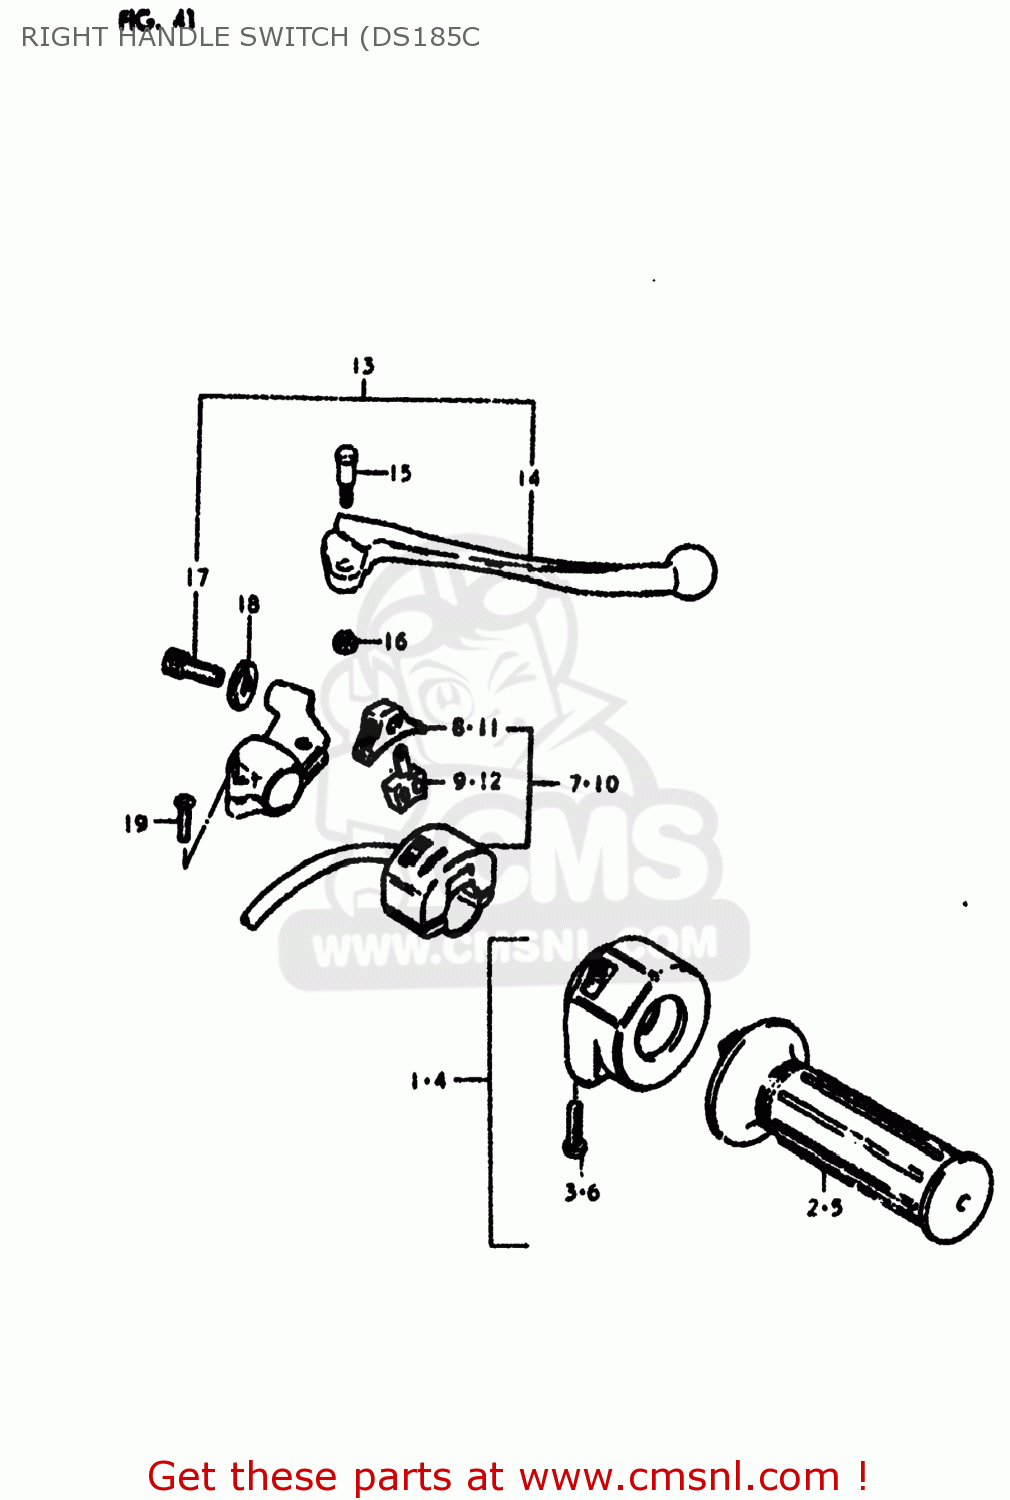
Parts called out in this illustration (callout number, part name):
1	GRIP ASSEMBLY,THROTTLE
2	GRIP,THROTTLE
3	SCREW 5X20
4	CASE ASSEMBLY,THROTTLE
5	GRIP,THROTTLE
6	SCREW
7	SWITCH ASSEMBLY,LIGHTING
8	KNOB,HANDLE SWITCH
9	BLOCK,LIGHTING/DIMMER
10	SWITCH ASSEMBLY,LIGHTING
11	KNOB,LIGHTING & DIMMER
12	BLOCK,LIGHTING/DIMMER
13	LEVER ASSEMBLY,BRAKE
14	LEVER,BRAKE
15	BOLT,LEVER
16	NUT 6MM
17	ADJUSTER,CABLE
18	NUT,CABLE ADJUSTER
19	SCREW
